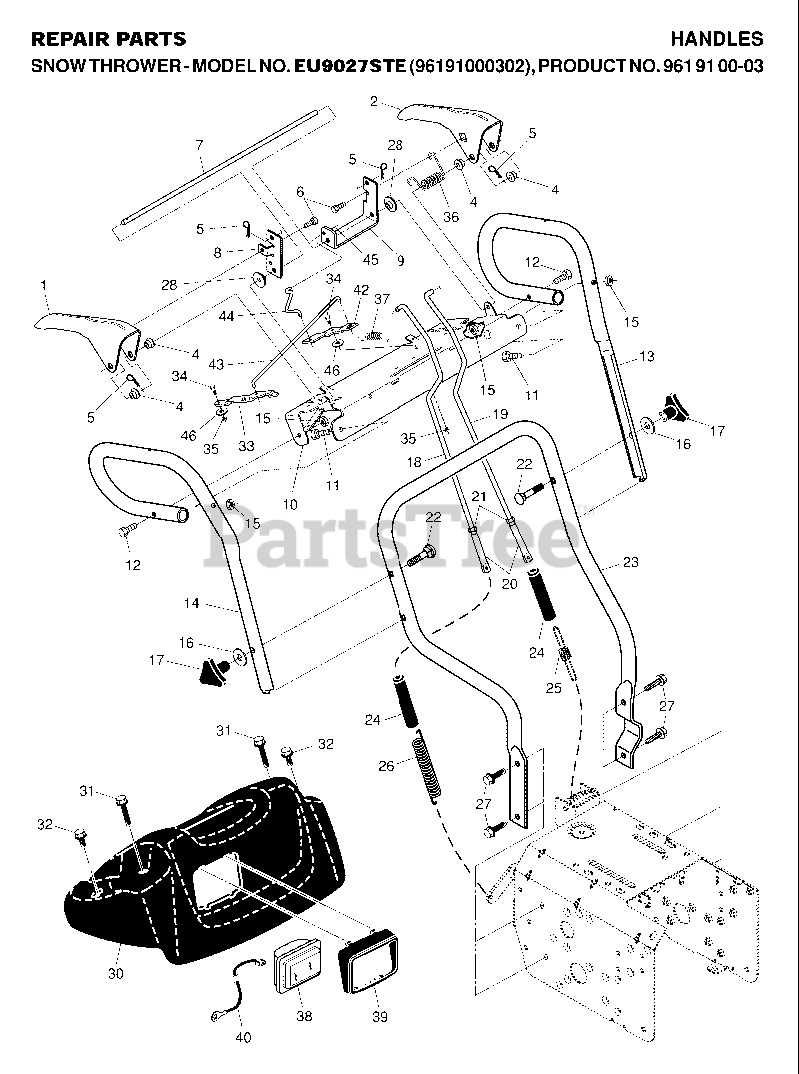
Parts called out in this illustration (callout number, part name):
1	LEVER, AUGER CONTROL, RH
2	LEVER, TRACTION DRIVE CONTROL,
4	BUSHING, FLANGE
5	SPRING RETAINER
7	ROD.INTERLOCK
8	ARM,IMPELLER ROD
9	ARM,TRACTION ROD
10	PANEL.CONTROL
11	HEX BOLT
13	HANDLE TUBE LH
14	HANDLE TUBE RH
15	NUT.LOCK.5/16-18
16	WASHER
17	KNOB.HANDLE.3/8.TRI-POINT.BLAC
18	ROD.ASM.IMPELLER
19	ROD.ASM.TRACTION.
20	ROD, END CONTROL
21	JAM NUT TI
22	BOLT 3/8-16 X 2-1/4
23	TUBE.LOWER.HANDLE.24.BLACK
24	SLEEVE, SPRING
25	SPRING, TRACTION DRIVE
26	SPRING, AUGER CONTROL
27	SCREW 3/8-16X1
28	BUSHING, IDLER PIVOT
30	PANEL.CONSOLE.SNOW
31	SCREW, HEX HD TAPPING #10-24 1
32	SCREW, HEX HEAD, TAPPING
33	LATCH.INTERLOCK
34	BOLT, SHOULDER
35	NUT **
36	RP SPRING, TORSION
37	SPRING LATCH
38	HEADLIGHT.HALOGEN.SNOW
39	BEZEL.HEADLIGHT.BLACK
40	HARNESS.WIRE.HALOGEN
42	LEVER.INTERLOCK
43	ROD.LATCH.INTERLOCK
44	ROD.ASM INTERLOCK
45	RETAINER CLIP
46	WASHER, NYLON FRICTION
